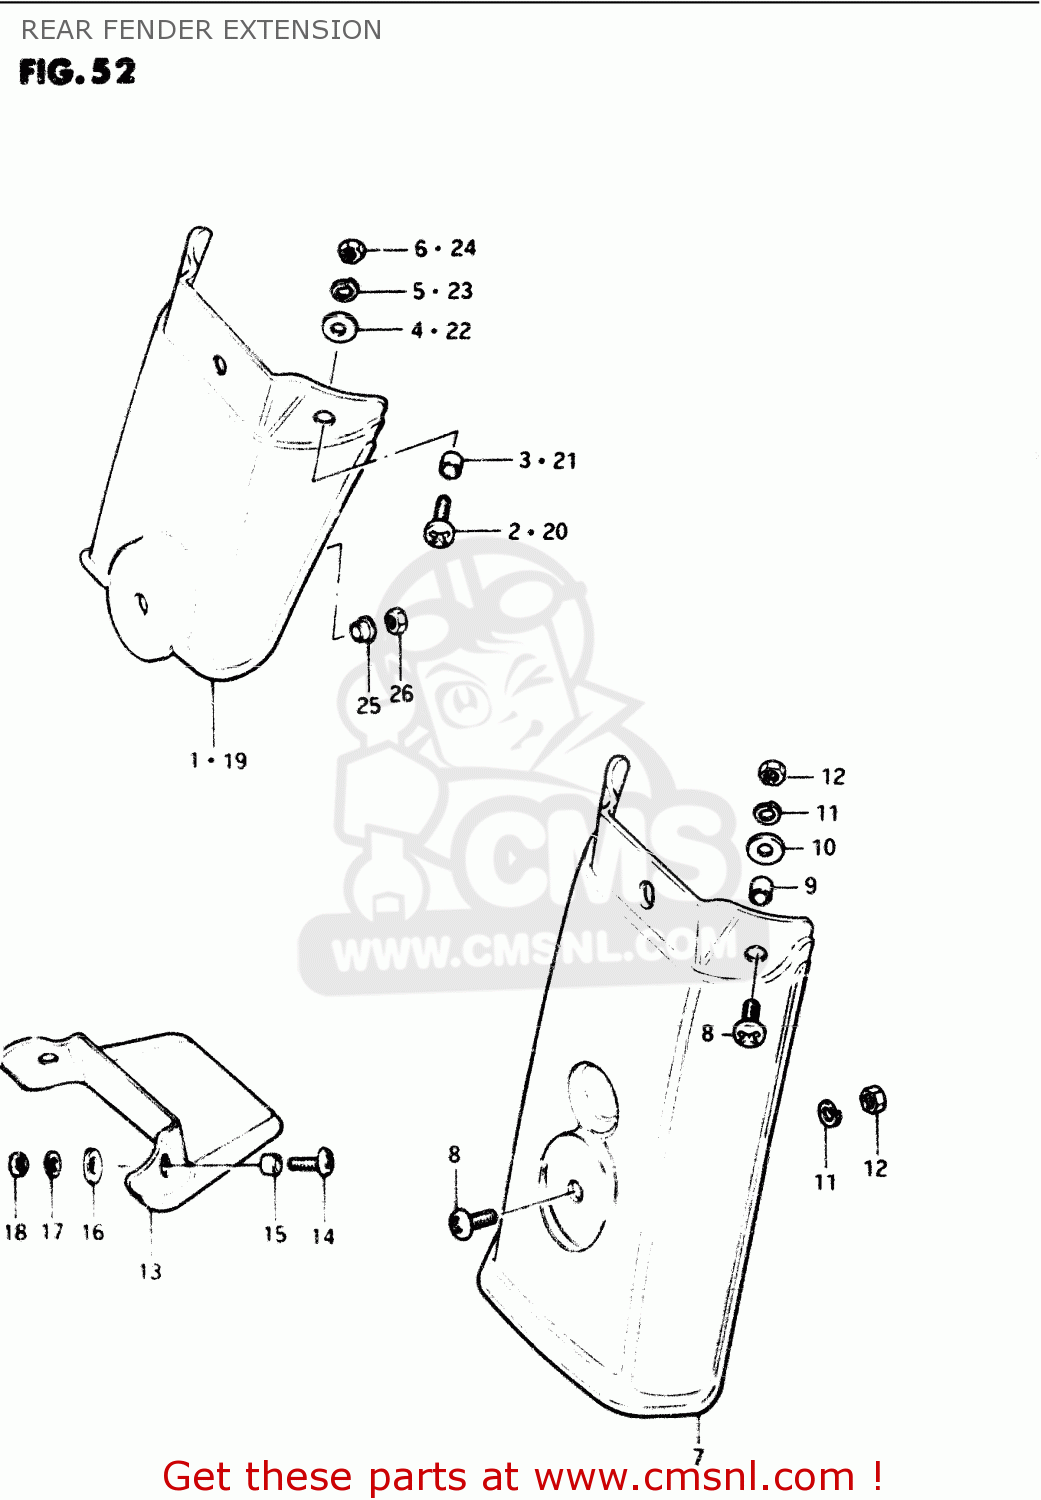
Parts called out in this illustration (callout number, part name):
1	EXTENSION,REAR FENDER
2	SCREW (6X15)
3	SPACER(6.2X8.3X5.7)
4	WASHER(6.5X18X1)
5	WASHER,LOCK
6	NUT
7	EXTENSION, REAR FENDER
8	SCREW (6X15)
9	SPACER(6.2X8.3X5.7)
10	WASHER(6.5X18X1)
11	WASHER,LOCK
12	NUT
13	EXTENSION,REAR FENDER
14	SCREW (6X15)
15	SPACER(6.2X8.3X5.7)
16	WASHER(6.5X18X1)
17	WASHER,LOCK
18	NUT
19	EXTENSION,REAR FENDER
20	SCREW (6X15)
21	SPACER(6.2X8.3X5.7)
22	WASHER(6.5X18X1)
23	WASHER,LOCK
24	NUT
25	SPACER
26	NUT
